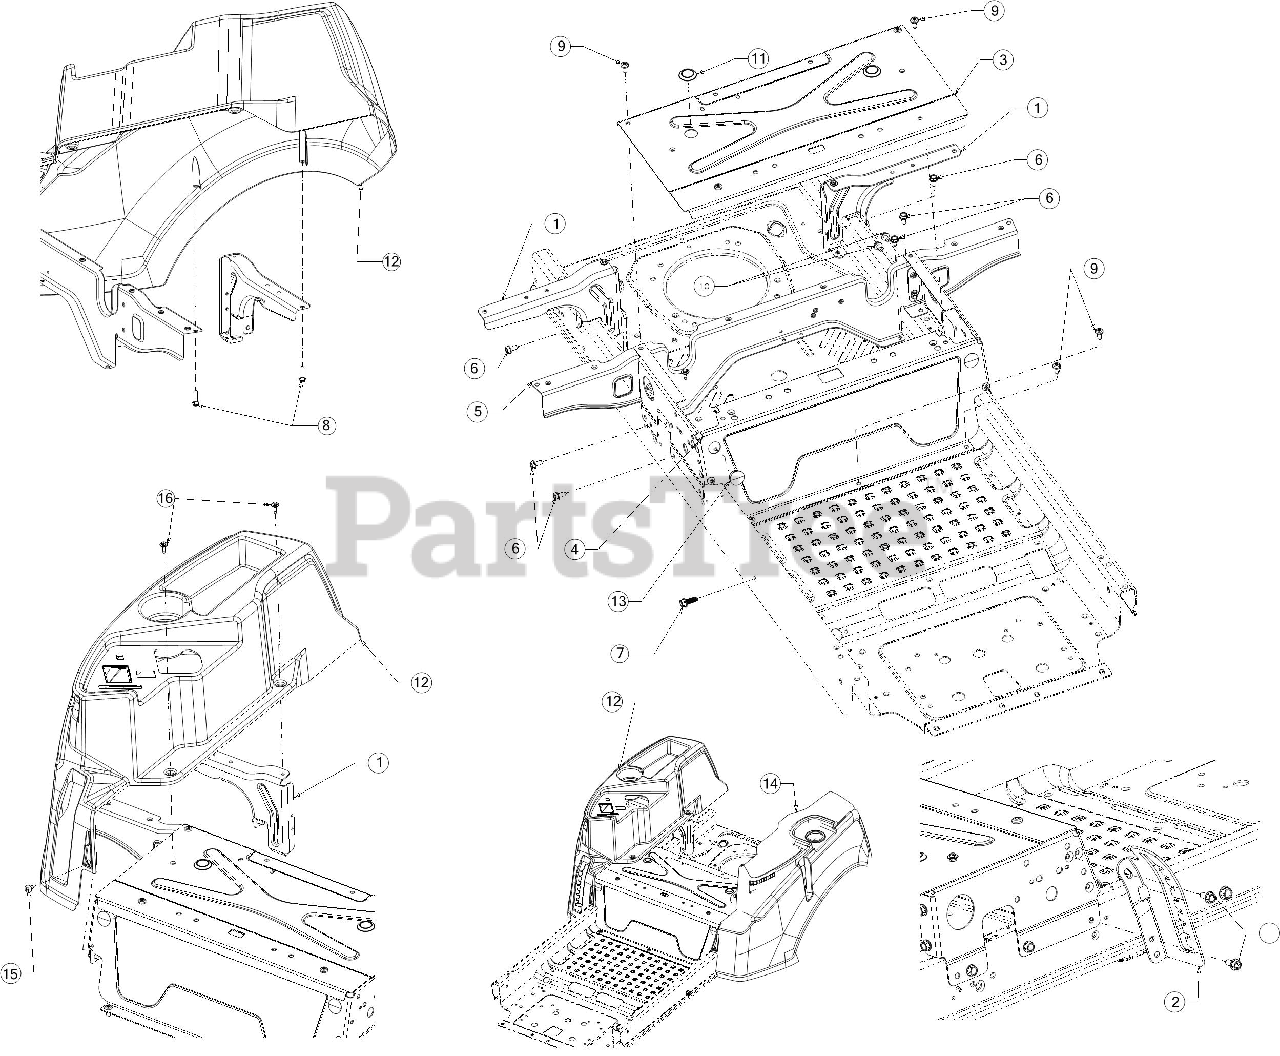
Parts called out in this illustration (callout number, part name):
1	REAR TANK BRACKET
2	HEIGHT INDEX BRACKET
3	SEATBOX TOP PLATE
4	SEAT FRAME
5	REAR SEATBOX BRACE
6	SCREW 5/16-18 X .750
7	SCREW 3/8-16 X 1
8	SCREW 5/16-14 X 1
9	SCREW 5/16-18 X .750
10	SCREW 5/16-18 x .500
12	CONSOLE-(RH)
13	PLASTIC PLUG
14	CONSOLE-(LH)
15	TORX SHOULDER SCREW 1/4-20
16	SHOULDER SCREW M6-1 .368 X.115
